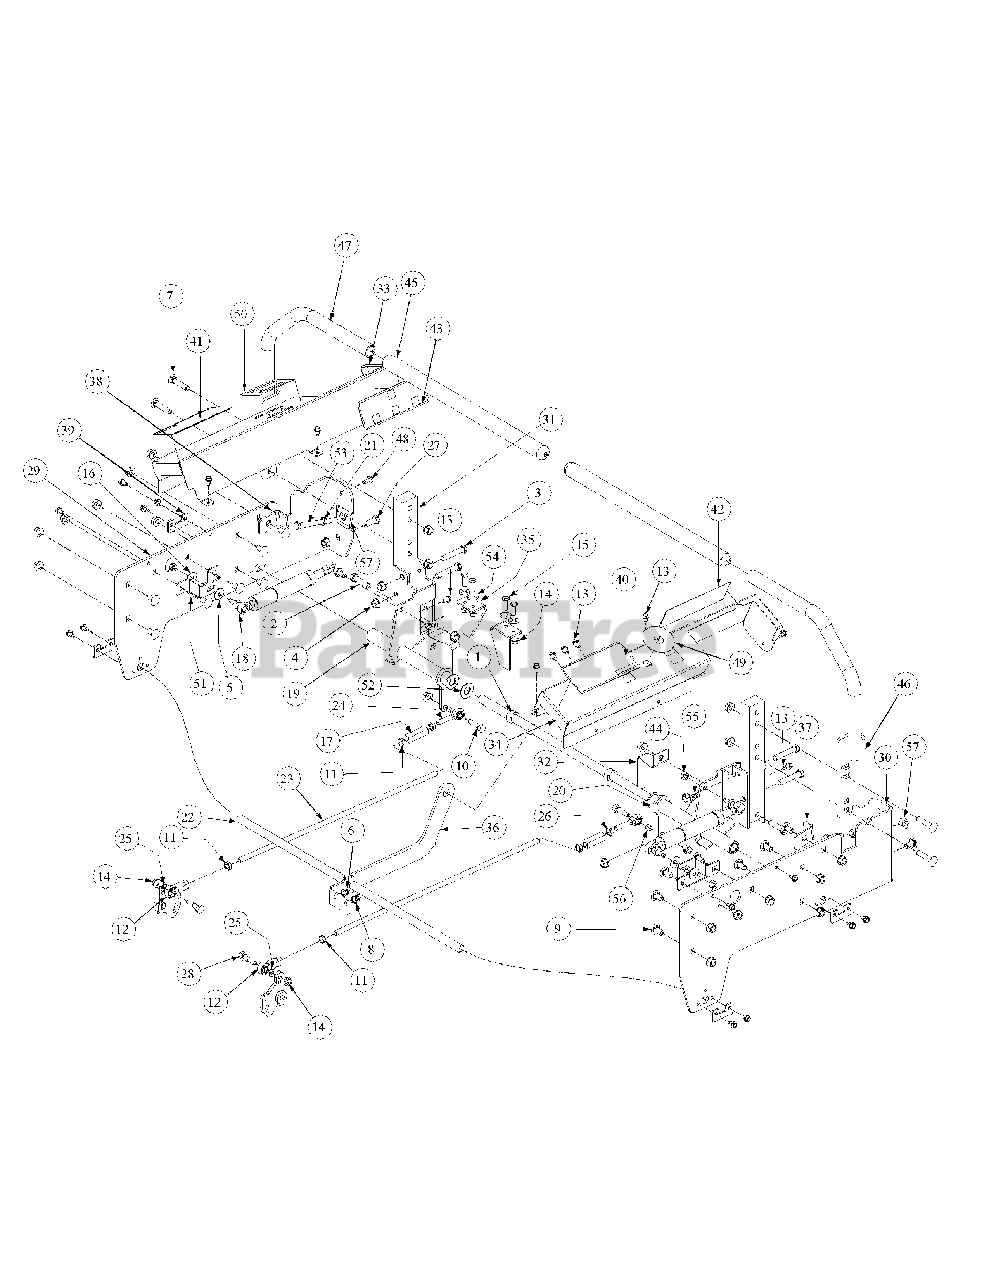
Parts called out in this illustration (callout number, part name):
1	Shaft Collar
2	HHCS, 3/8-16, 2.00
3	HHCS, 3/8-16, 2.25
4	Hex Nut, 3/8-16, Lock Flange
5	External Washer, 3/8
6	HHCS, 1/4-20, .750
7	Hex Carriage Screw, 3/8-16, 1.75
8	Lock Washer, 1/4 Zinc
9	Carriage Bolt, 3/8-16 x .75
10	Capscrew, 3/8-16 x 1-3/4
11	Hex Jam Nut, 3/8-24
12	B/Joint, 3/8-24, Right Hand Female
13	Screw, TT, 1/4-20, 0.5, Hex Index Washer
14	Nut, Lock, Hex Flange, 5/16-18
15	Hex, Cap Screw, 5/16-18 x 3/4
16	Belle Washer, .325 x .930 x .045
17	Turnbuckle
18	Cylinder Return to Neutral
19	Hub Assy, Control LH Bearing
20	Hub Assy, Control RH Bearing
21	Nut, 3/8-16, Jam
22	Shaft Control Brake Steering
23	Rod Connector 3/8 OD x 14.25
24	B/Joint, 3/8-24, Left Hand Female
25	5/16, Lock Washer
26	Nut, 3/8-24, Jam, LH Third
27	HHCS, 5/16-18 x 1.0
28	Screw, Shoulder Control Rod
29	Side Panel, Control, Left
30	Side Panel, Control, Right
31	Mounting Handle
32	Lever, Safety Switch
33	Control Panel, LH
34	Control Panel, RH
35	Switch Mounting Bracket, Lapbar
36	Link Mounting Control Shaft, Bracket
39	Holder Shaft, Park Brake
40	Decal , Right Hand Console
41	Decal, Left Hand Console
42	Decal Right Hand Control
43	Decal, Left Hand Control
44	Nut, Hex, Center Lock, M8
45	Grip, 1.0
46	Lapbar, Weldment, Right Handle
47	Lapbar, Weldment, Left Handle
48	Screw, TT, 1/4-20, 0.75, Hex Index Washer
49	Label, Ignition, 2.5 Diameter
50	Label, Control, Throttle and Choke
51	Bracket Assembly, Mount Dampener
52	Flat Washer, 5/8 Nylon
53	HHCS, 3/8-16, 3.00
54	Flat Washer, 5/16
55	Grease Fitting, 90°.
56	Spacer, .385ID x .625 OD x >50 Lg
57	U-Nut, 3/8-16, .75
